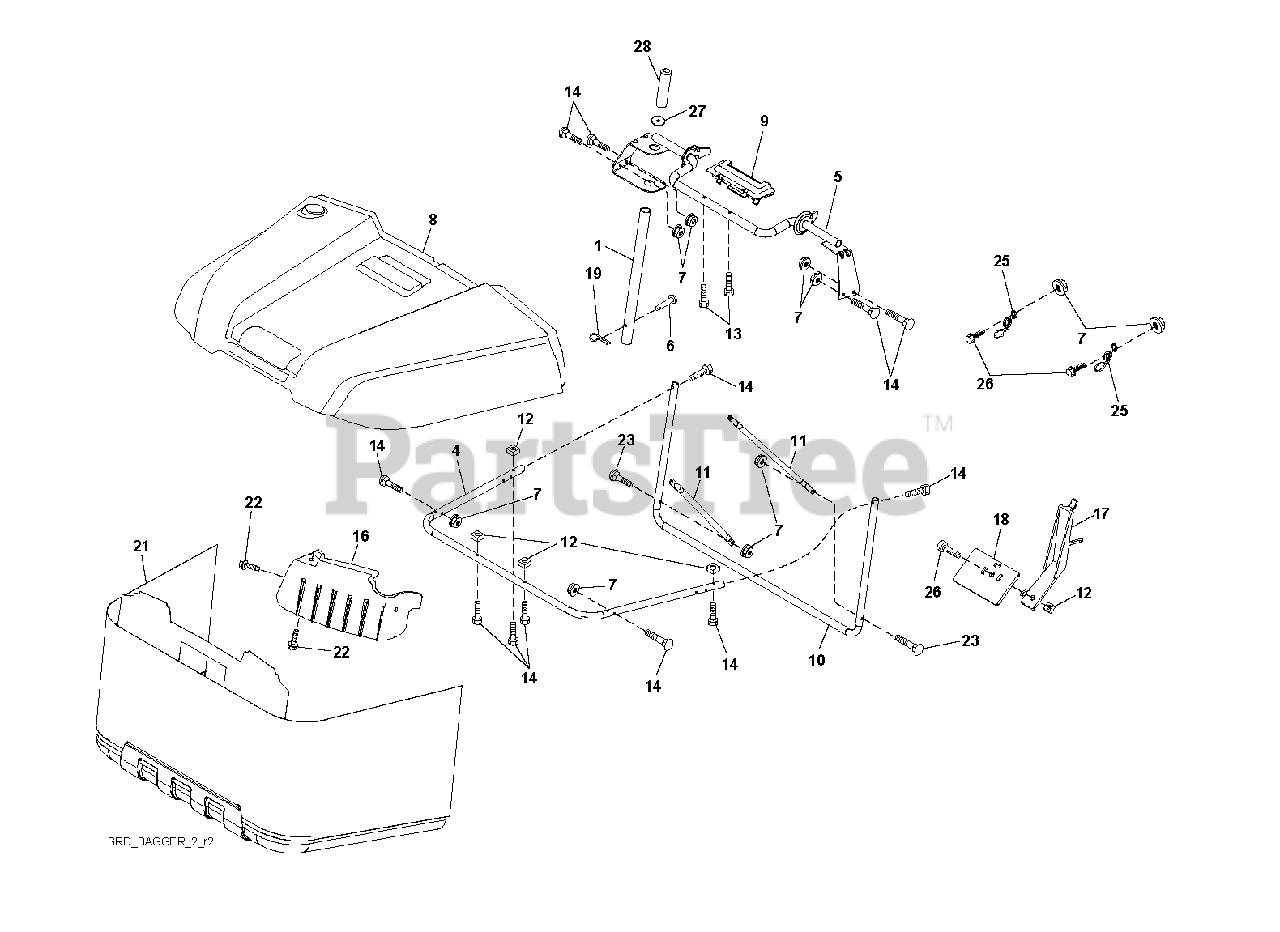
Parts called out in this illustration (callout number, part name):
1	TUBE.PNT.HDL.BAGGER.
6	RIVET,DRILLED
7	NUT T
19	PIN.COTTER.5/16.BOW TI
22	SCREW.HI-LO.CONSOLE
26	SCREW HEX CRT
28	GRIP.HANDLE.BLACK
